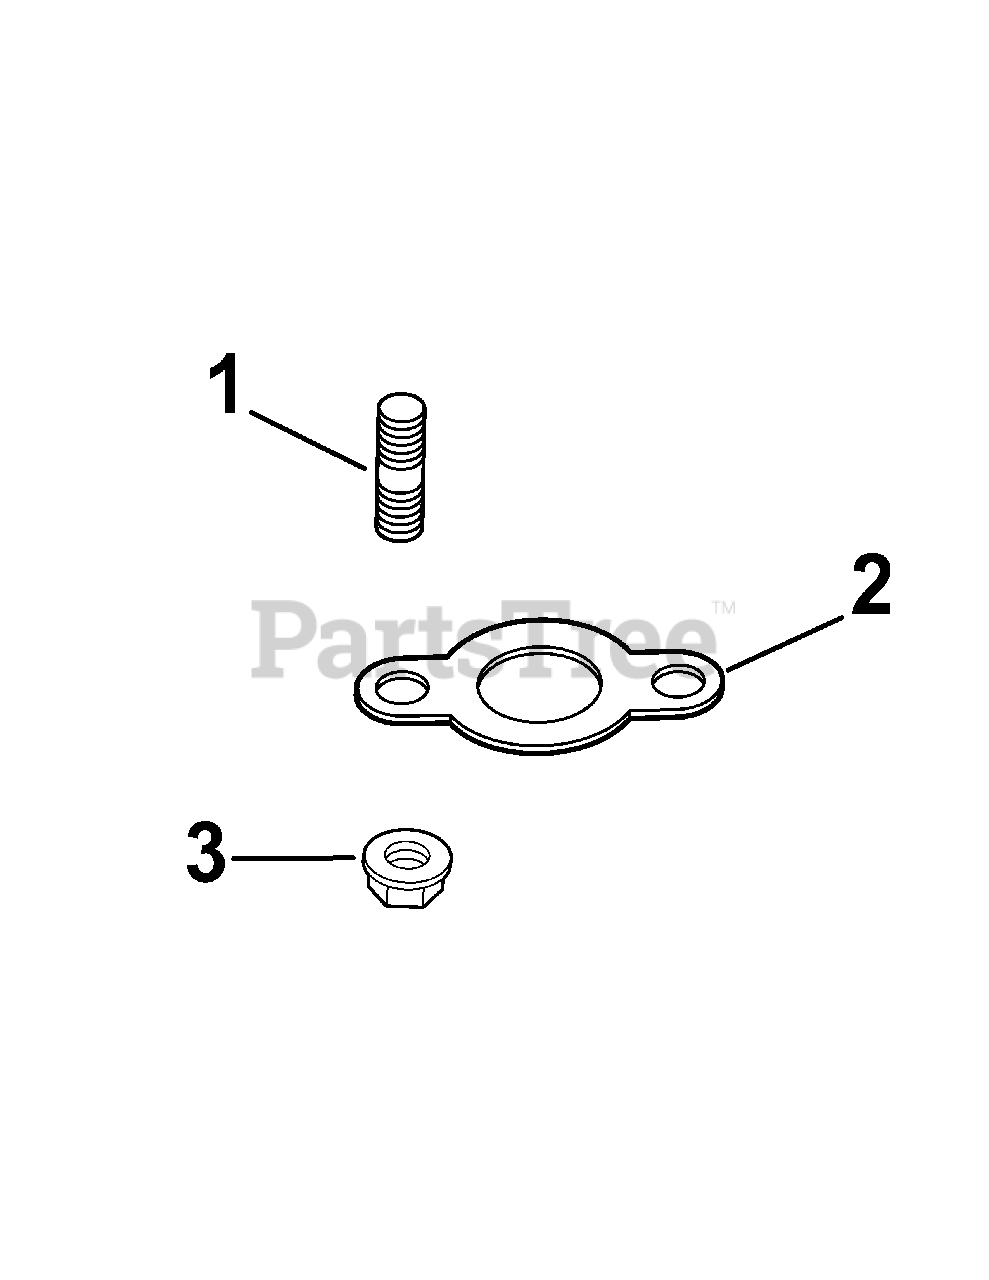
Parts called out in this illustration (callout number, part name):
1	Stud M8x1.25x33 (4)
2	Gasket, exhaust manifold (2)
3	Nut, hex. flange M8x1.25 (5)
